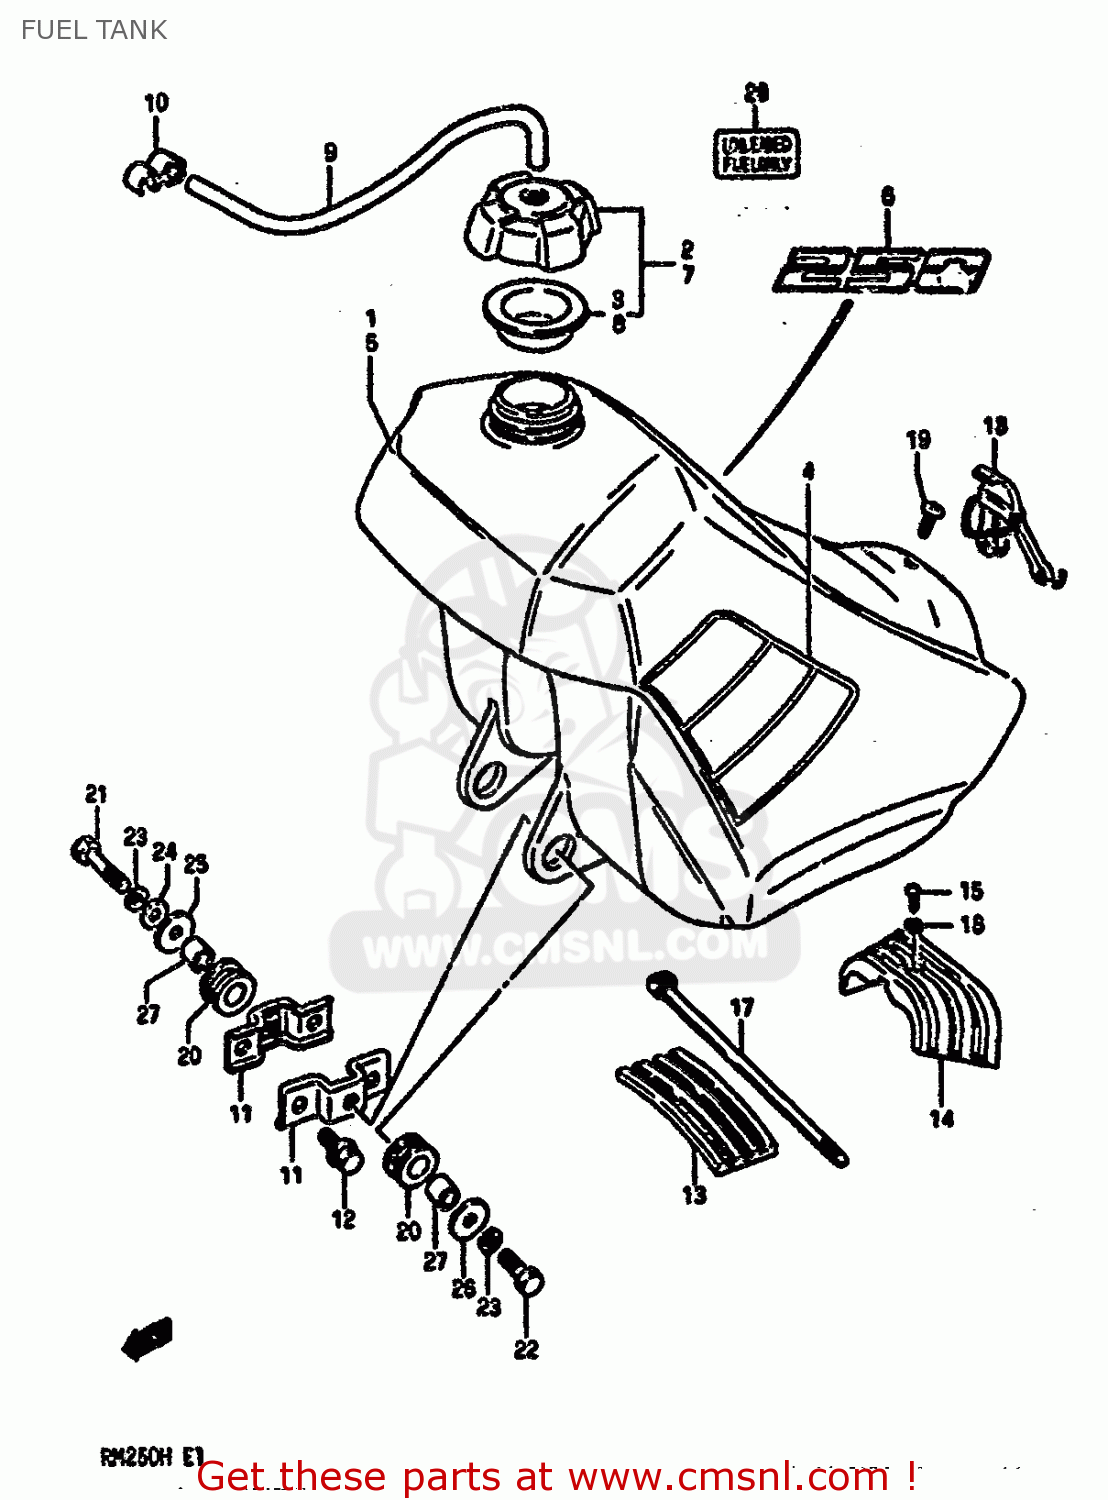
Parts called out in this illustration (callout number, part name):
1	TANK ASSEMBLY,FUEL
2	CAP SET,FUEL TANK
3	GASKET,FUEL TANK CAP (NAS)
4	TAPE SET,FUEL TANK
5	TANK SET,FUEL
6	TAPE,FUEL TANK (250)
7	CAP SET,FUEL TANK
8	GASKET,FUEL TANK CAP (NAS)
9	HOSE
10	CLAMP,BREATHER HOSE
11	BRACKET,FUEL TANK
12	BOLT 8X16
13	CUSHION,FUEL TANK UPR FR
14	CUSHION,FUEL TANK
15	SCREW
16	WASHER
17	CLAMP
18	BAND,FUEL TANK RR
19	SCREW (6X15)
20	CUSHION
21	BOLT 8X50
22	BOLT
23	LOCK WASHER
24	WASHER
25	WASHER(8.5X26X1.2)
26	WASHER
27	SPACER(8.4X12X12)
28	LABEL,UNLEADED FUEL
